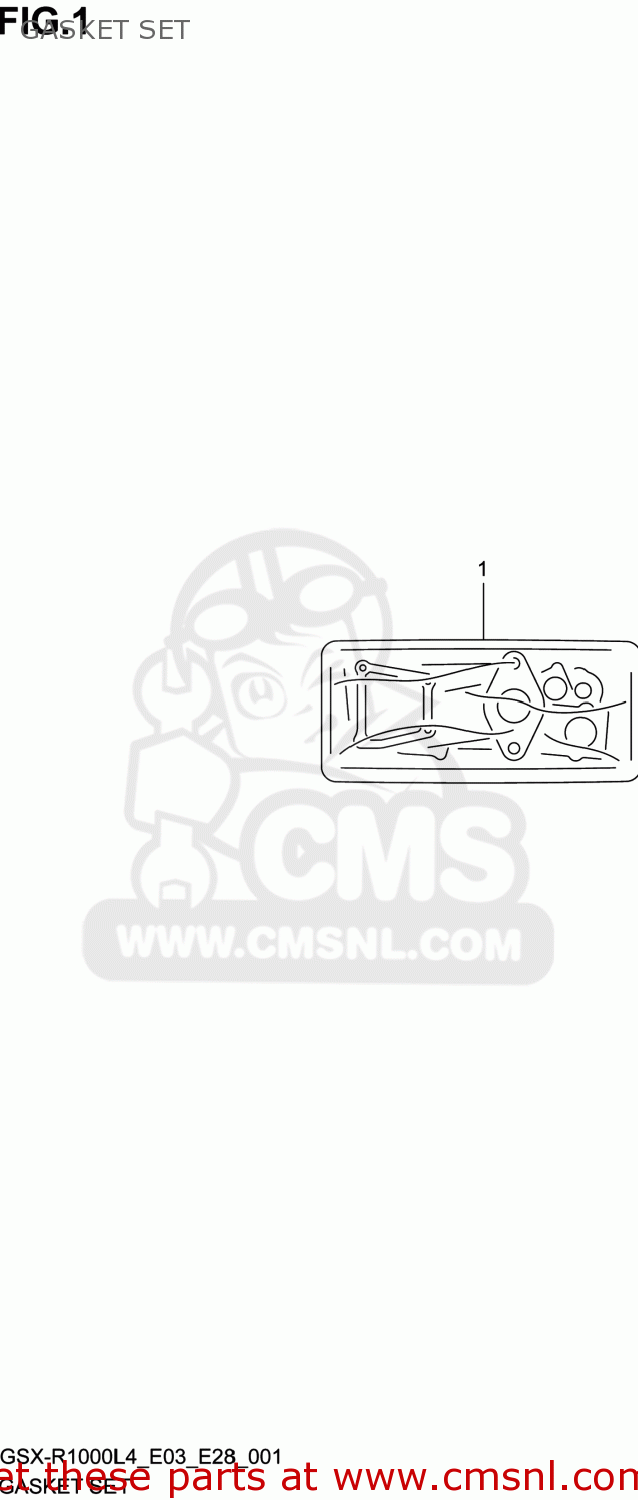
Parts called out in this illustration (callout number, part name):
1	GASKET SET (NAS)
2	GASKET,CYLINDER HEAD (NAS)
3	GASKET,CYL HEAD COVER NO.1 (NAS)
4	GASKET,CYL HEAD COVER NO.2
5	GASKET,2ND AIR PASSAGE (NAS)
6	WASHER,CYL HEAD COVER
7	GASKET,CLUTCH COVER (NAS)
8	GASKET,GENERATOR COVER (NAS)
9	GASKET,OIL PAN(ASB) (NAS)
10	GASKET,TENSIONER ADJUSTER (NAS)
11	GASKET,EXHAUST PIPE (NAS)
